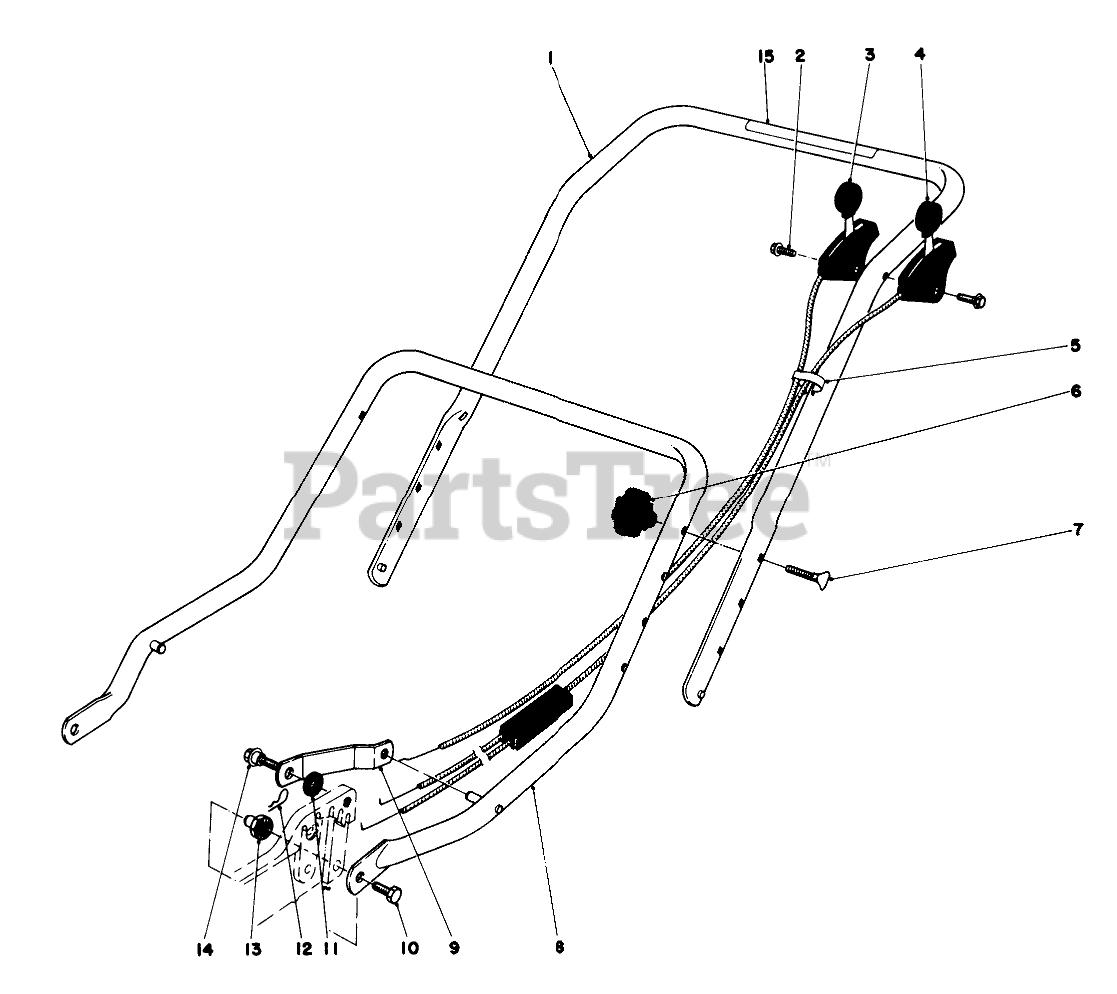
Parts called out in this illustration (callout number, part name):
1	Upper Handle
3	Throttle Control
4	Traction Control
7	HANDLE SCREW
8	Lower Handle
9	HANDLE LATCH
10	SCREW-HH
11	SPACER
12	PIN-COTTER, HAIR
13	HANDLE PIVOT NUT
14	SCREW-SHOULDER
15	Decal
